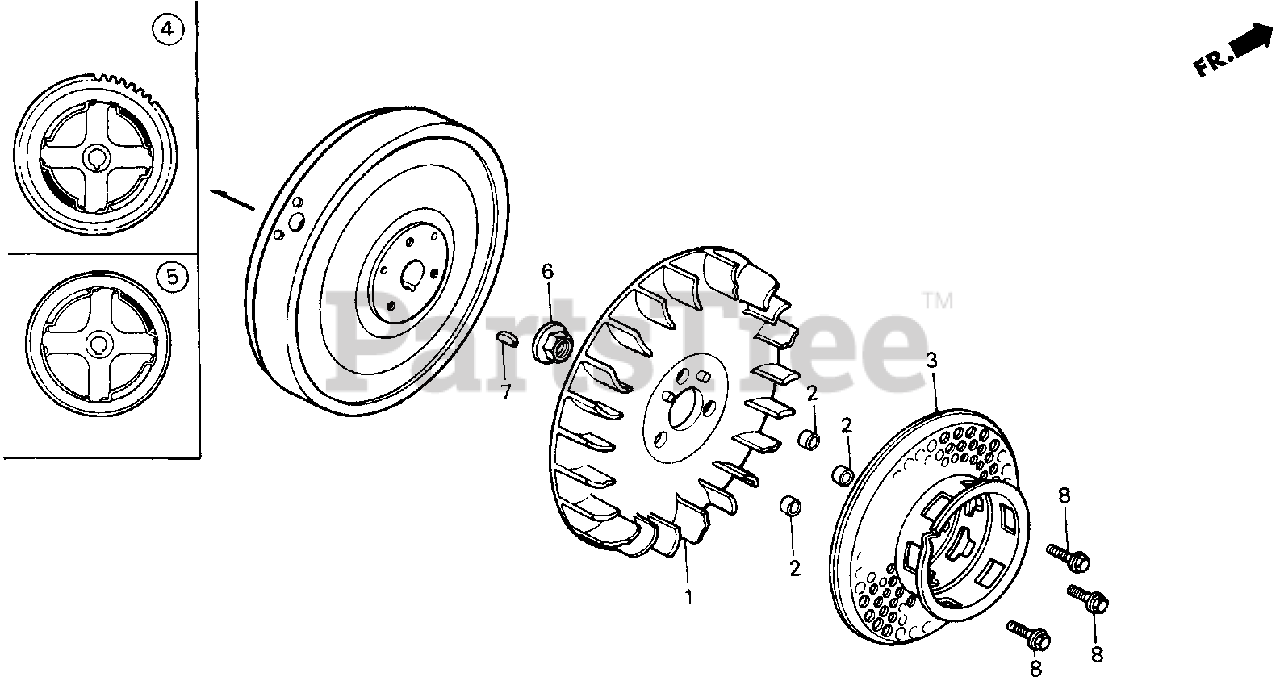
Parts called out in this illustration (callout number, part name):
1	FAN, COOLING
2	COLLAR, FAN
3	PULLEY, STARTER
6	NUT, SPECIAL (14MM)
7	KEY, SPECIAL WOODRUFF (25X18)
8	BOLT, FLANGE (6X16)
